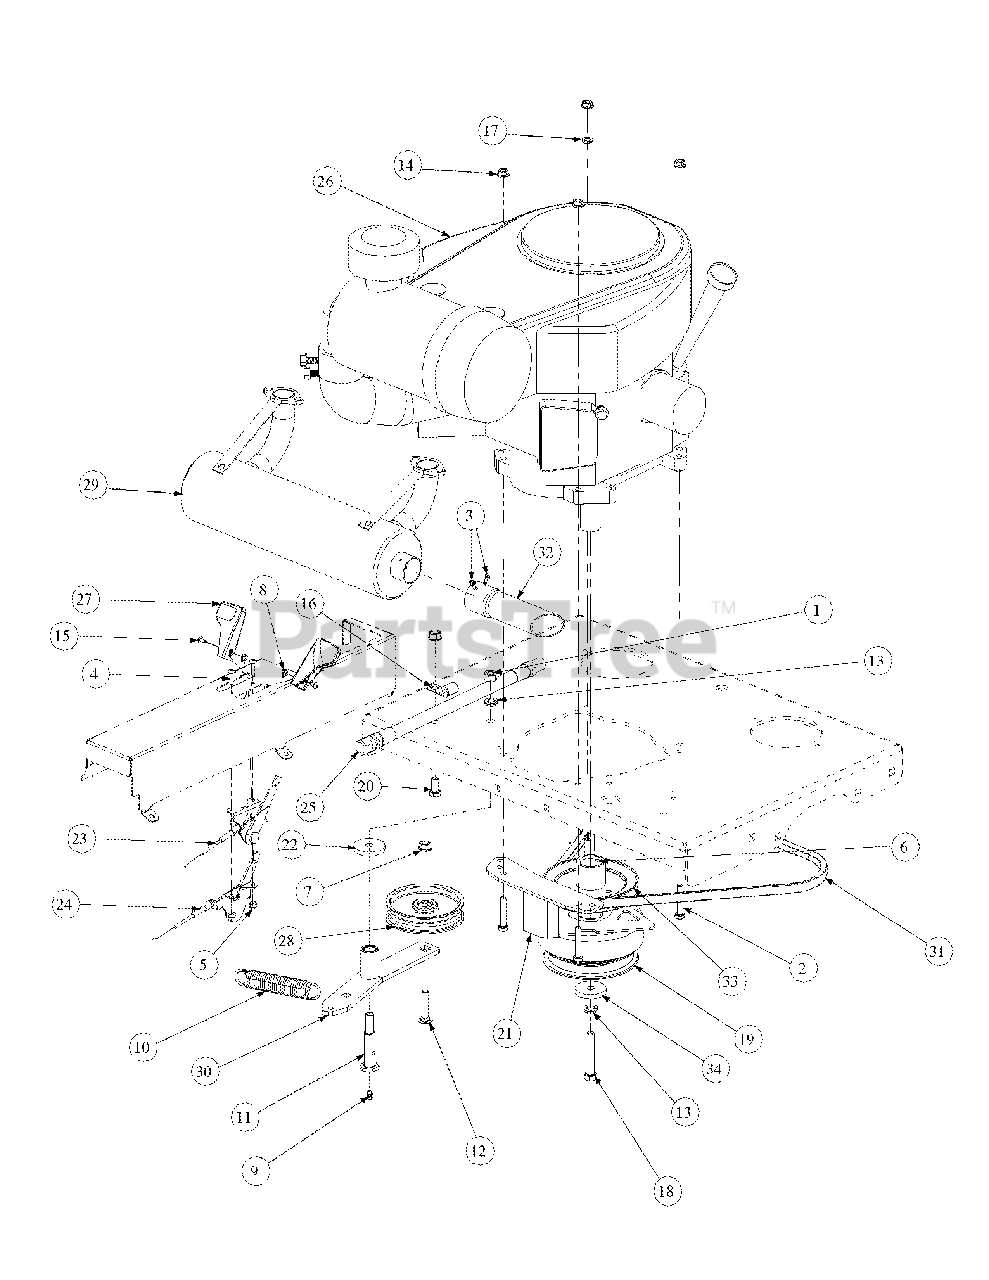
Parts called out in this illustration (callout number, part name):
1	Hex Nut, 7/16-14
2	HHCS, 5/16-18, 1-3/4
3	Screw, #8-32 x 0.375
4	Round Hd. Machine Screw, 10-32 x 3/4
5	Lock Nut, Nylon Insert, 10-32
6	Key, 1/4 x 1/4 x 3
7	Flange Lock, Hex Nut, 3/8-16
8	Nut Washer, W/Star, 8-32
9	Grease Fitting, 1/4-28 x 3/16
10	Extension Spring, 1.0 OD x 5.125
11	Shoulder Screw, 7/16-14
12	Hex Carriage Screw, 3/8-16, 1.75
13	Lock Washer, 7/16
14	Hexflange Lock Nut, 5/16-18
15	Machine Screw, 8-32, .375
16	Clip, Heat Shield Cable
17	Flat Washer, 5/16
18	Capscrew, 7/16-20 x 2.50
19	Clutch Brake, 1.125 ID
20	Hex Cap Screw, 3/8-16, .750
21	Retainer Clutch Assembly, Ogura
22	Flat Washer, 7/16 ID x 1.75 OD x .25
23	Choke, Control Cable, 43.0
24	Throttle, Control Cable, 39.0
25	Oil Drain Hose
26	25HP Twin Engine, Kawasaki
27	Control Throttle Knob
28	Flat Pulley with Flanges
29	Muffler Accessory, Kawasaki
30	Engine Idler Arm Casting
31	V Belt, A Section x .47.3
32	Muffler Accessory Exhaust Tube
33	Pump Drive Pulley
34	Flat Washer, 7/16 ID x 1.75 OD x .25
